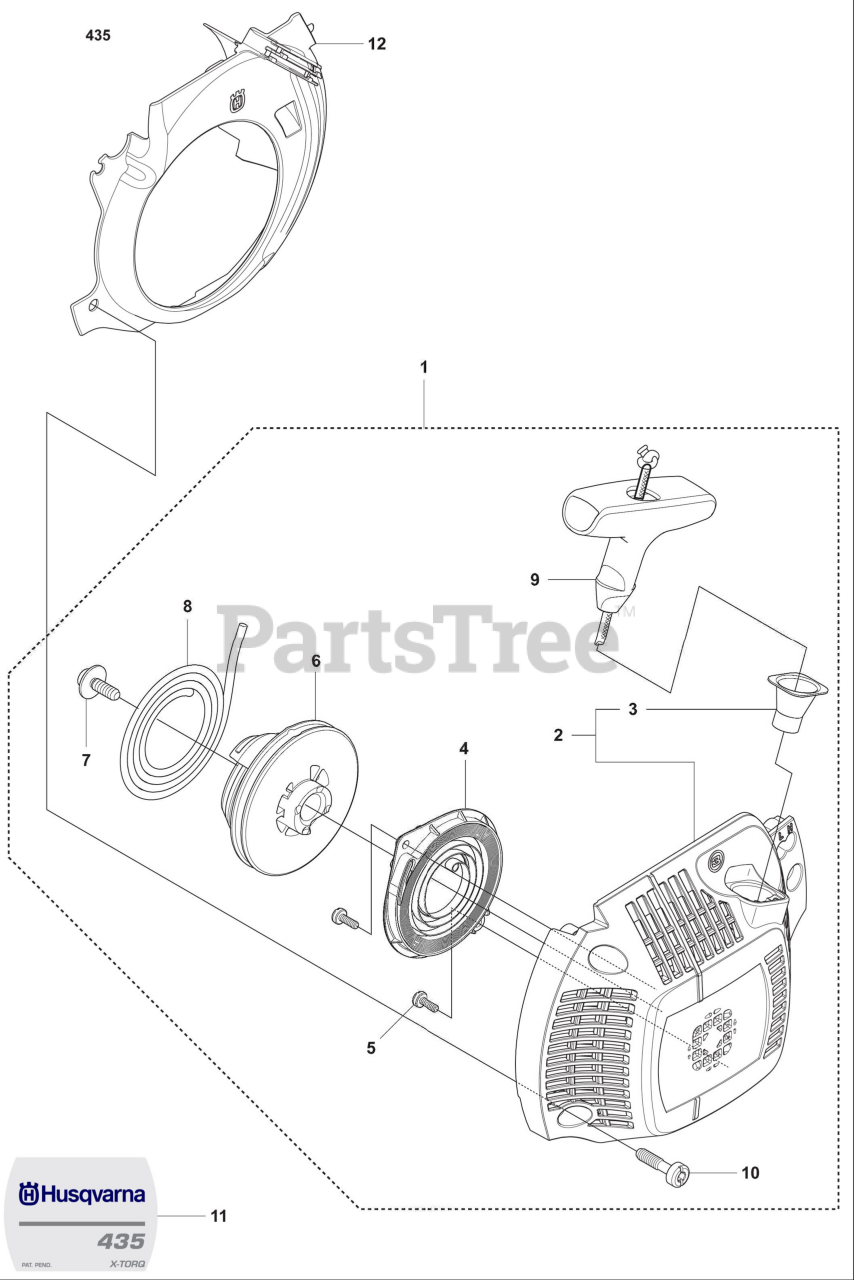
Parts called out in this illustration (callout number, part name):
1	Recoil Starter Assembly
2	Starter Housing
3	Sleeve
4	Cassette Assembly Spring
5	Screw
6	Starter Pulley
7	Screw
8	Starter Rope
9	Handle
10	Recoil Starter Screw
11	Label
12	Air Cooling Conductor
